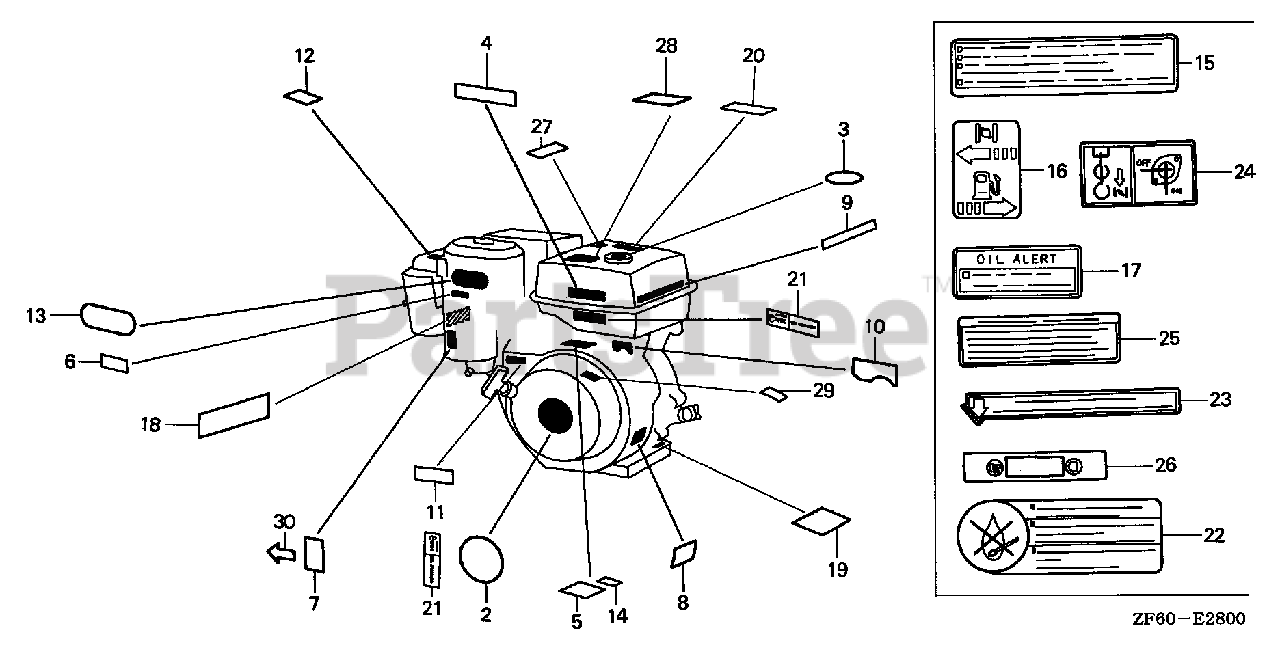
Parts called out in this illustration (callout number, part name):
2	MARK, EMERGENCY SWITCH INDICATION
2	EMBLEM (13. (HONDA)
5	LABEL, CAUTION (ENGLISH, ETC.)
7	MARK, CHOKE
11	MARK, THROTTLE INDICATION
17	MARK, OIL ALERT (ENGLISH)
21	LABEL, E-SPEC (15.5X27.5)
